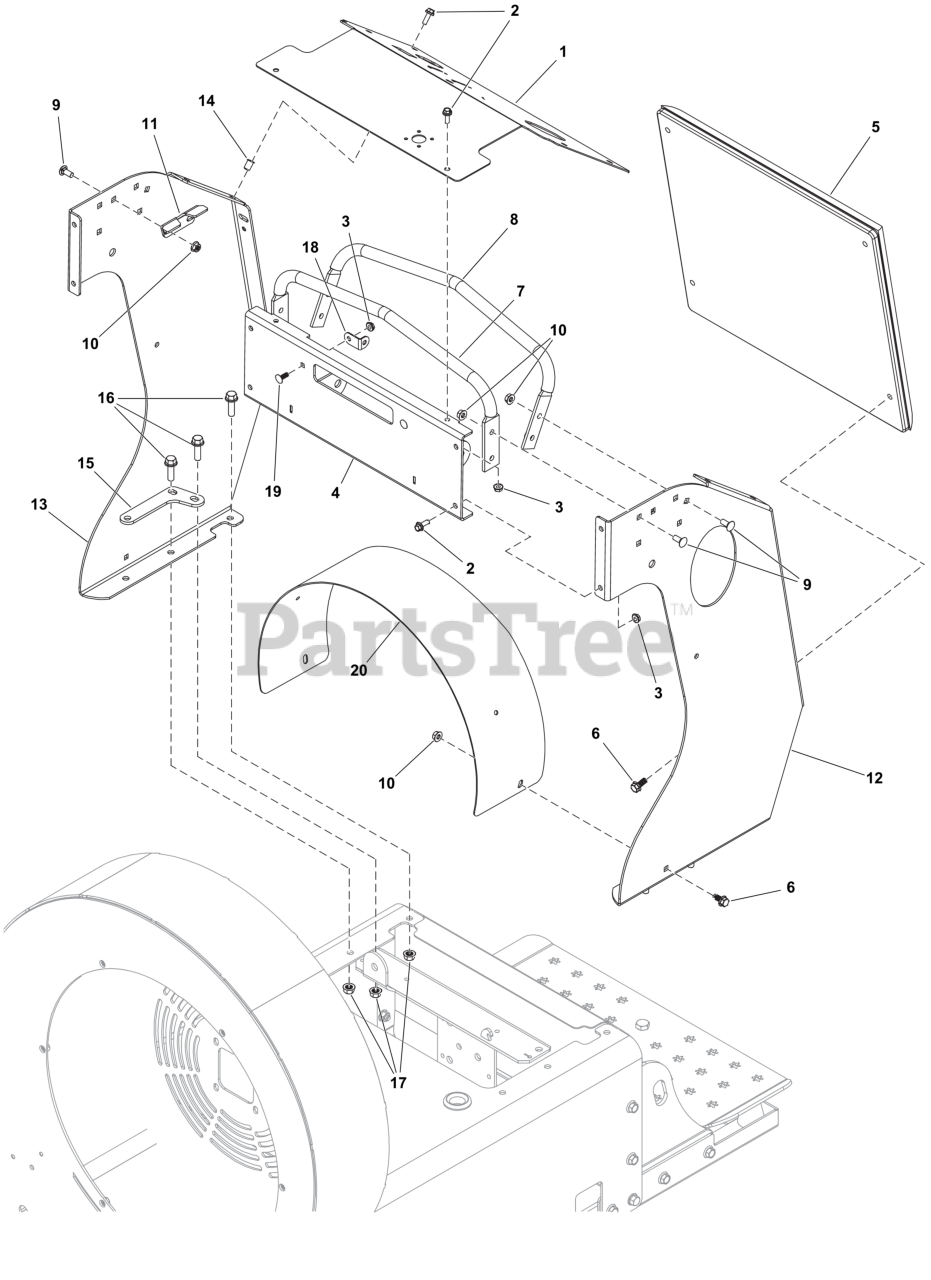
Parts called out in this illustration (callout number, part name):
1	PLATE, Control Panel
4	WELD, DASH FRONT PANEL - ORG
5	PAD, KNEE
6	SCREW, 5/16-18
7	HANDLE, FRONT
8	HANDLE, REAR
9	BOLT, 5/16-18 X 3/4",
10	NUT, 5/16-18 HEX SERR
12	CONTROL TOWER X3, LH - TX ORG
13	CONTROL TOWER X3, RH - ORG
18	BRACKET, L Headlight Mount
19	BOLT, 1/4-20X.750, SQ
20	PLATE, BELT GUARD COVER X3 - TX ORG
